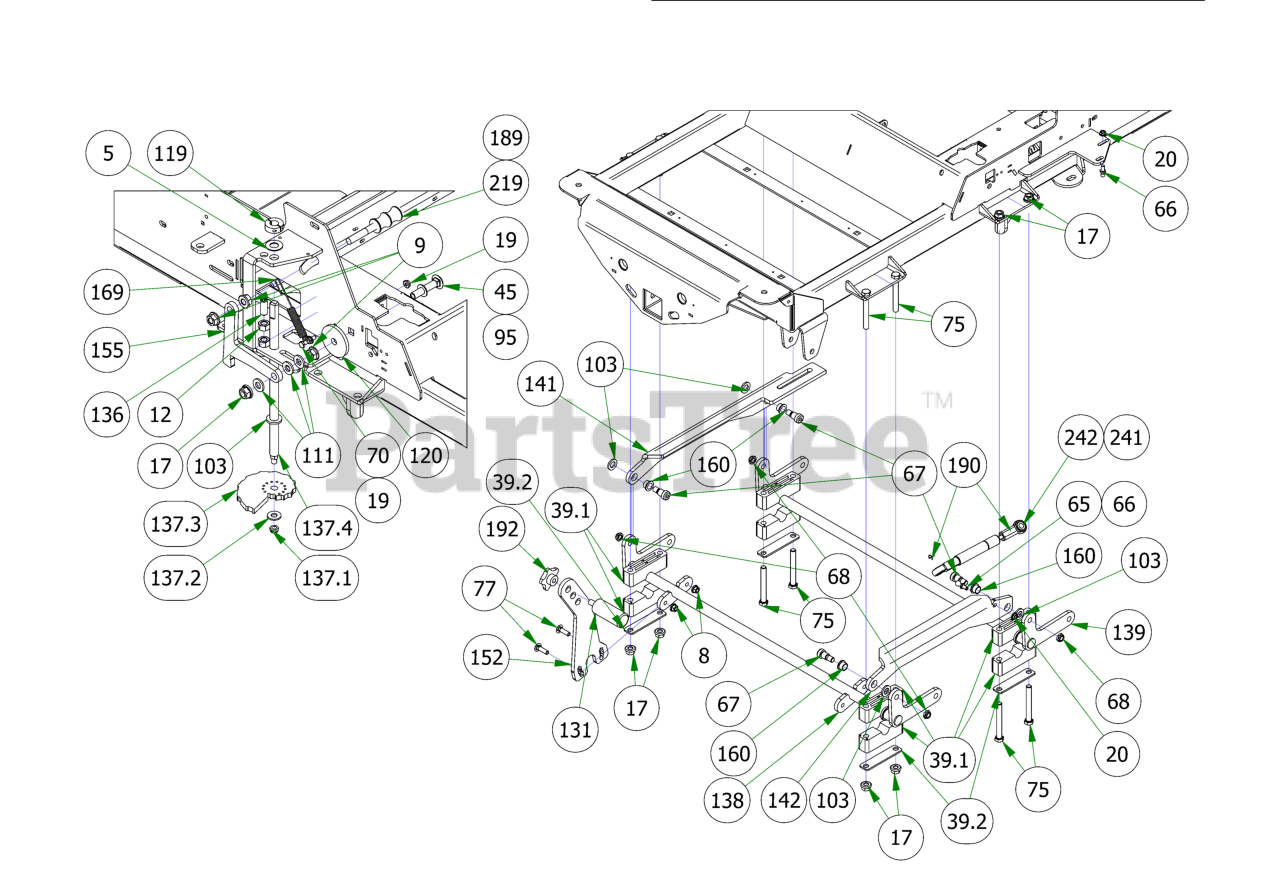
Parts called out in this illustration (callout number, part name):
5	.625 ID x 1.250 OD x .062 THK F/W Nylon
8	3/8-16 NYLON INSERT FLANGE LOCKNUT (GR.F) ZINC
9	1/2-13 HEX SERRATED FLANGE NUT HARD/ZINC
12	1/2-13 HEX NUT ZINC
17	1/2-13 NYLON INSERT FLANGE LOCKNUT ZINC
19	1/4-20 HEX SERRATED FLANGE NUT HARD/ZINC
20	5/16-18 HEX SERRATED FLANGE NUT HARD/ZINC
39	Pillow Block Assembly
39.1	Two Piece Pillow Block
39.2	Two Piece Pillow Block Strap
45	2 1/2 x 1/2 Carriage Bolt
65	13mm Damper Ball Stud-Steering
66	10mm Damper Ball Stud-XP Linkage
67	5/8 X 5/8 SOCKET SHOULDER BOLT ZINC YELLOW
68	1/2-13 NYLON INSERT JAM LOCKNUT ZINC
70	1/4-20 X 1-1/4 HEX CAP SCREW (GR.5) ZINC
75	1/2-13 X 4 HEX CAP SCREW (GR.8) ZINC YELLOW
77	3/8-16 X 1-1/4 CARRIAGE BOLT ZINC
95	.517 SQ WDTH ID X .937 OD X .060 THICK F/W PHOS/OIL
103	.635 ID X 1.120 OD X .140 THICK FLAT WASHER NYLON
111	.505 ID X 1.000 OD X .125 THICK FLAT WASHER NYLON
119	5/8" Split Collar
120	MZ Deck Idler Spacer
131	Knurled Pedal
136	Dial Rod Plunger
137	2019 Outlaw Gen2 Deck Height Dial Rod Assy
137.1	3/8-24 Nylon Insert jam locknut
137.2	3/8" Flat Washer
137.3	2019 Deck Height Cam
137.4	2019 Outlaw Gen2 Dial Rod
138	2019 Outlaw Actuator - Front
139	2019 Outlaw Actuator - Rear
141	2019 Actuator Linkage – Right – Black
142	2019 Actuator Linkage - Left - Black
152	Foot Lift Upright Lever
155	2019 Outlaw Deck Travel Lock
160	.627 ID X .753 OD X .500 LGTH X 1.000 FLG OD X .094 FLG THICK FLANGED BEARING OIL-IMPREG BRNZ
169	Brake Spring
189	Seat Bracket Pin
190	Security Ring - PC744 (72" DECK ONLY)
192	Foot Pedal Knob 1/2-13
219	Travel Lock Rubber Grip
224	2019 Renegade Gas Frame - Powdercoated
241	250lb Gas Spring - 61" Deck
242	300lb Gas Spring - 72" Deck
